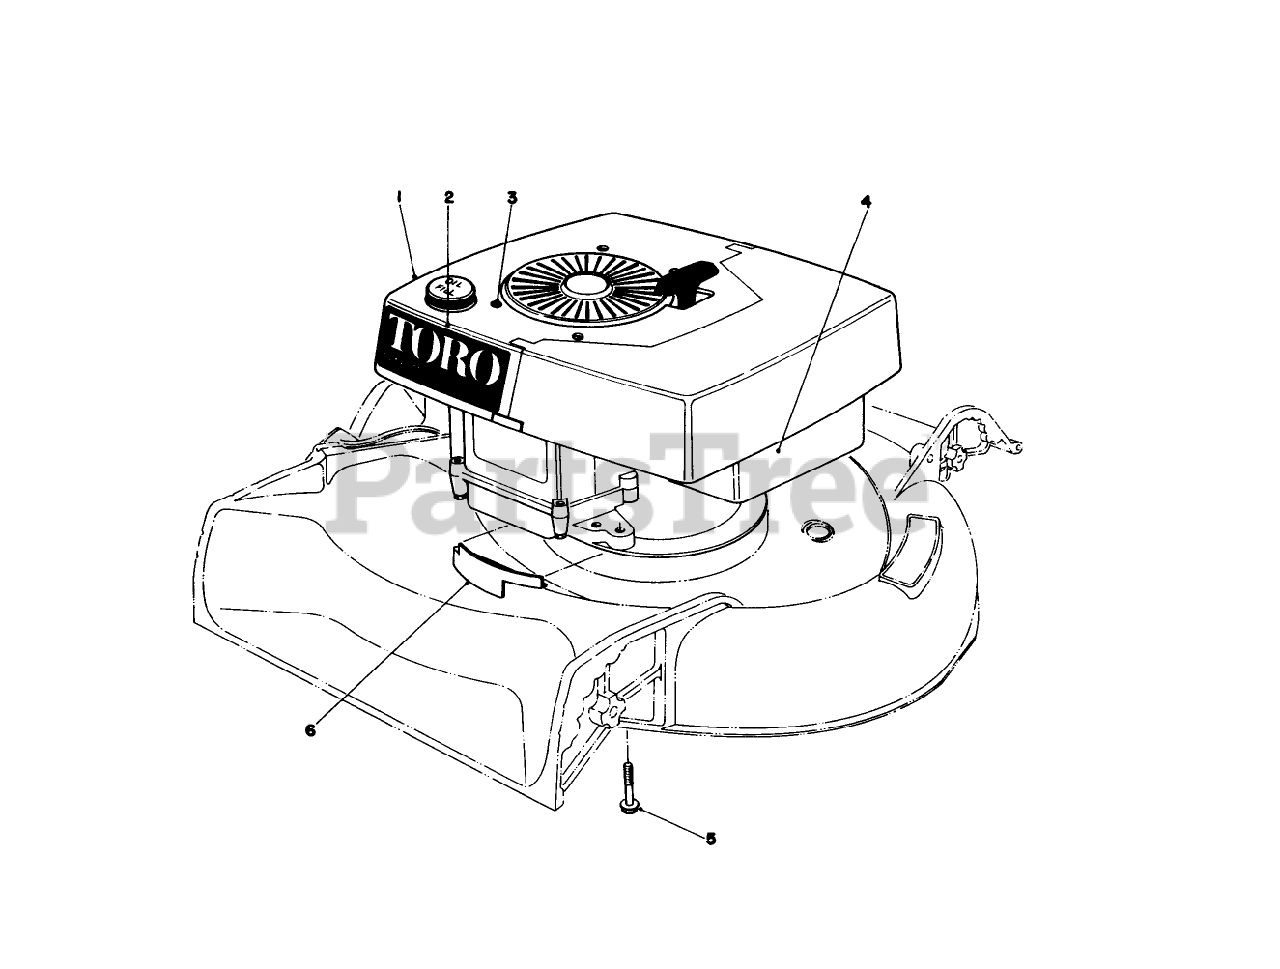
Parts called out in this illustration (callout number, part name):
1	SHROUD
4	Engine
5	3/8-16 X 2-3/4 CAPSCR
6	HOUSING CAP
